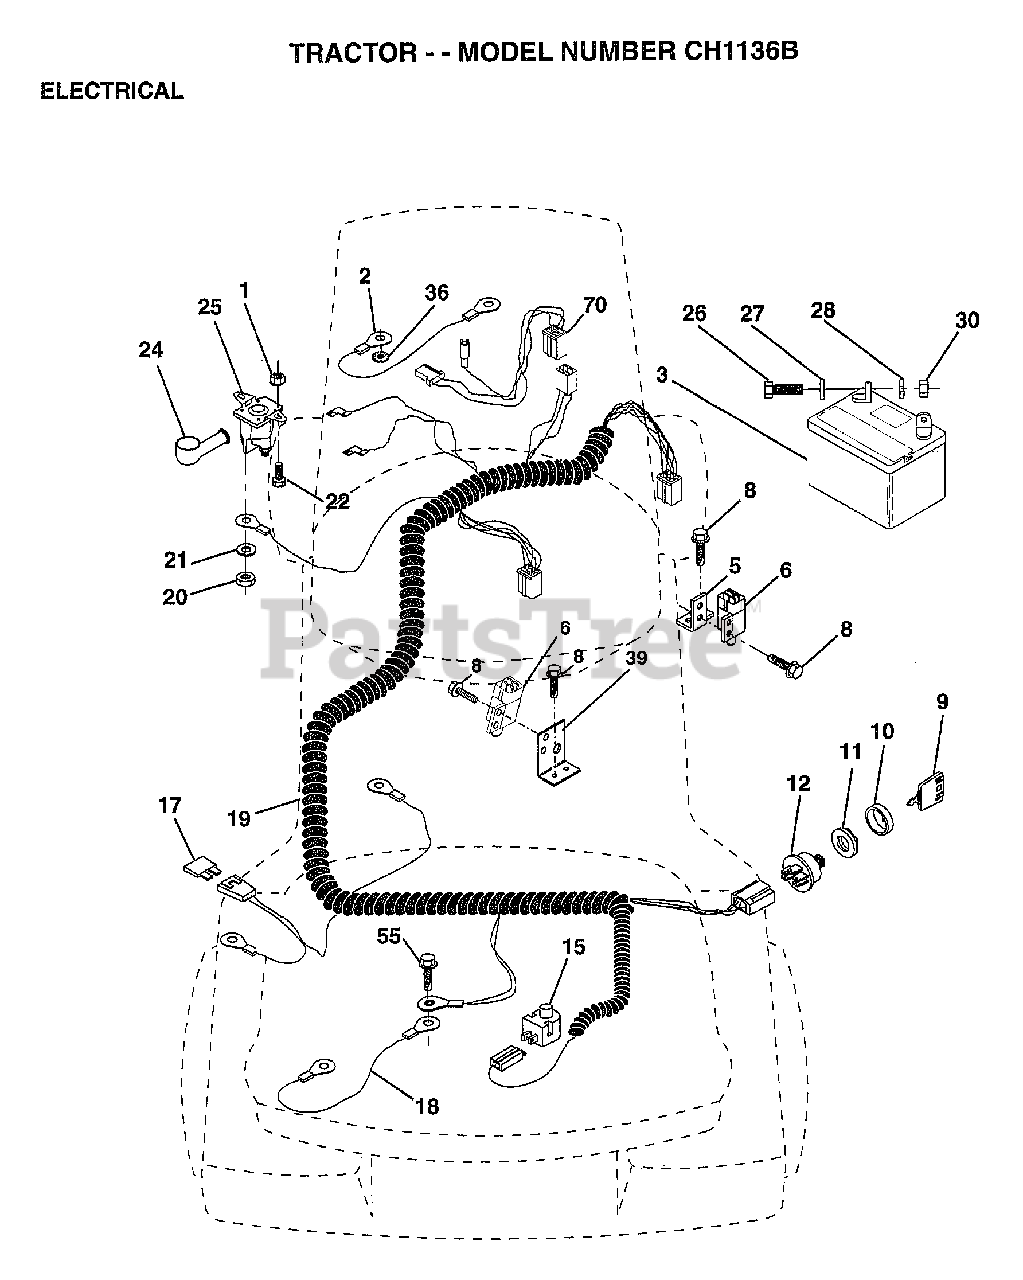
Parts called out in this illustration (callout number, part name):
1	NUT HXKEP 1/4X20
2	CABLE ASM.
5	BRACKET LT
6	SWITCH INTERLOCKT
8	SCREW
9	KEY STEEL DELTA
10	COVER KEY SWITCH
15	SWITCH SEAT
17	FUSE HYT
18	CABLE ASSY
19	HARNESS.IGN.FEND.
20	NUT
22	BOLT HXHD FIN
26	BOLT LT
27	WASHER
28	LOCKWASHER
36	LOCKWASHER
39	BRACKET SWT CLUTC
55	SCREW LT
70	HARNESS ENG DUAL
